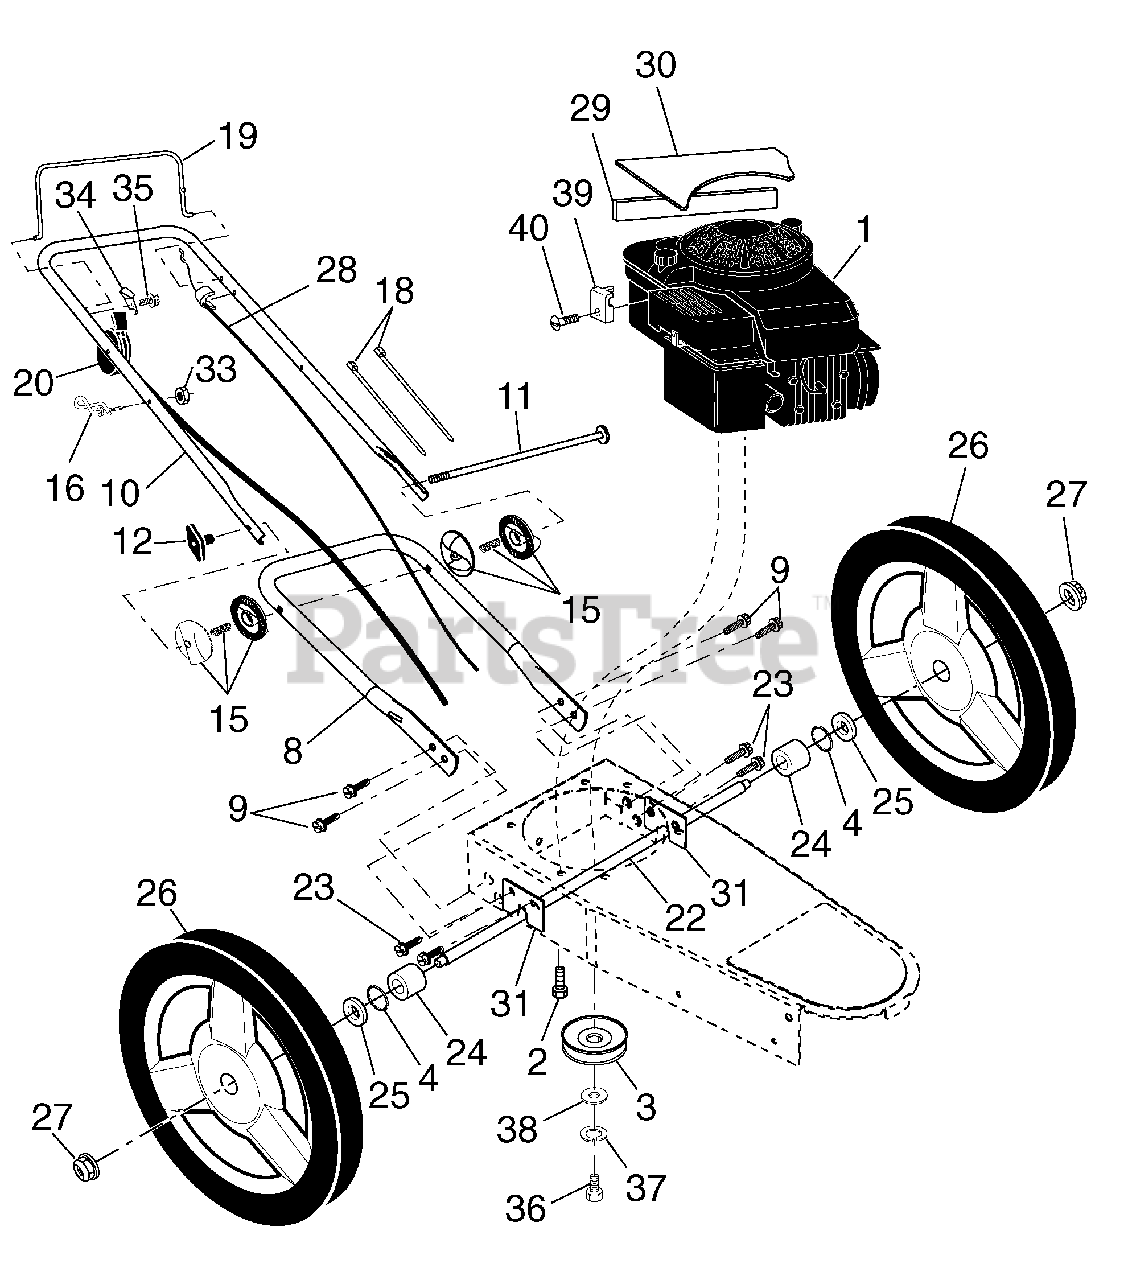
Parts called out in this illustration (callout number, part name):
2	Bolt, Engine Mounting 3/8-16
3	Pulley, Engine
8	Handle, Lower
9	Screw, Hex Washer Head 5/16-18 x 3/4
10	Handle, Upper
11	Bolt, Handle
12	Knob, Handle
15	Handle Adjuster Assembly
16	Guide, Rope
18	Wire Tire
19	Control Bar
20	Throttle Control
22	Axle Shaft Assembly
23	Screw, Hex Washer Head 5/16-18 x 3/4
24	Washer, Axle
25	Washer, Flat 1/2
26	Wheel & Tire Assembly 12 x 1-3/4
27	Locknut, Hex 3/8-16
28	Drive Control Cable
29	Decal, Warning
30	Decal, Warning
31	Bracket, Axle
33	Nut, Hex
34	Bracket, Upstop
35	Screw #10-24 x 5/8
36	Bolt, Hex Head
37	Washer, Lock
38	Washer, Flat, Hardened
39	Clamp, Cable
